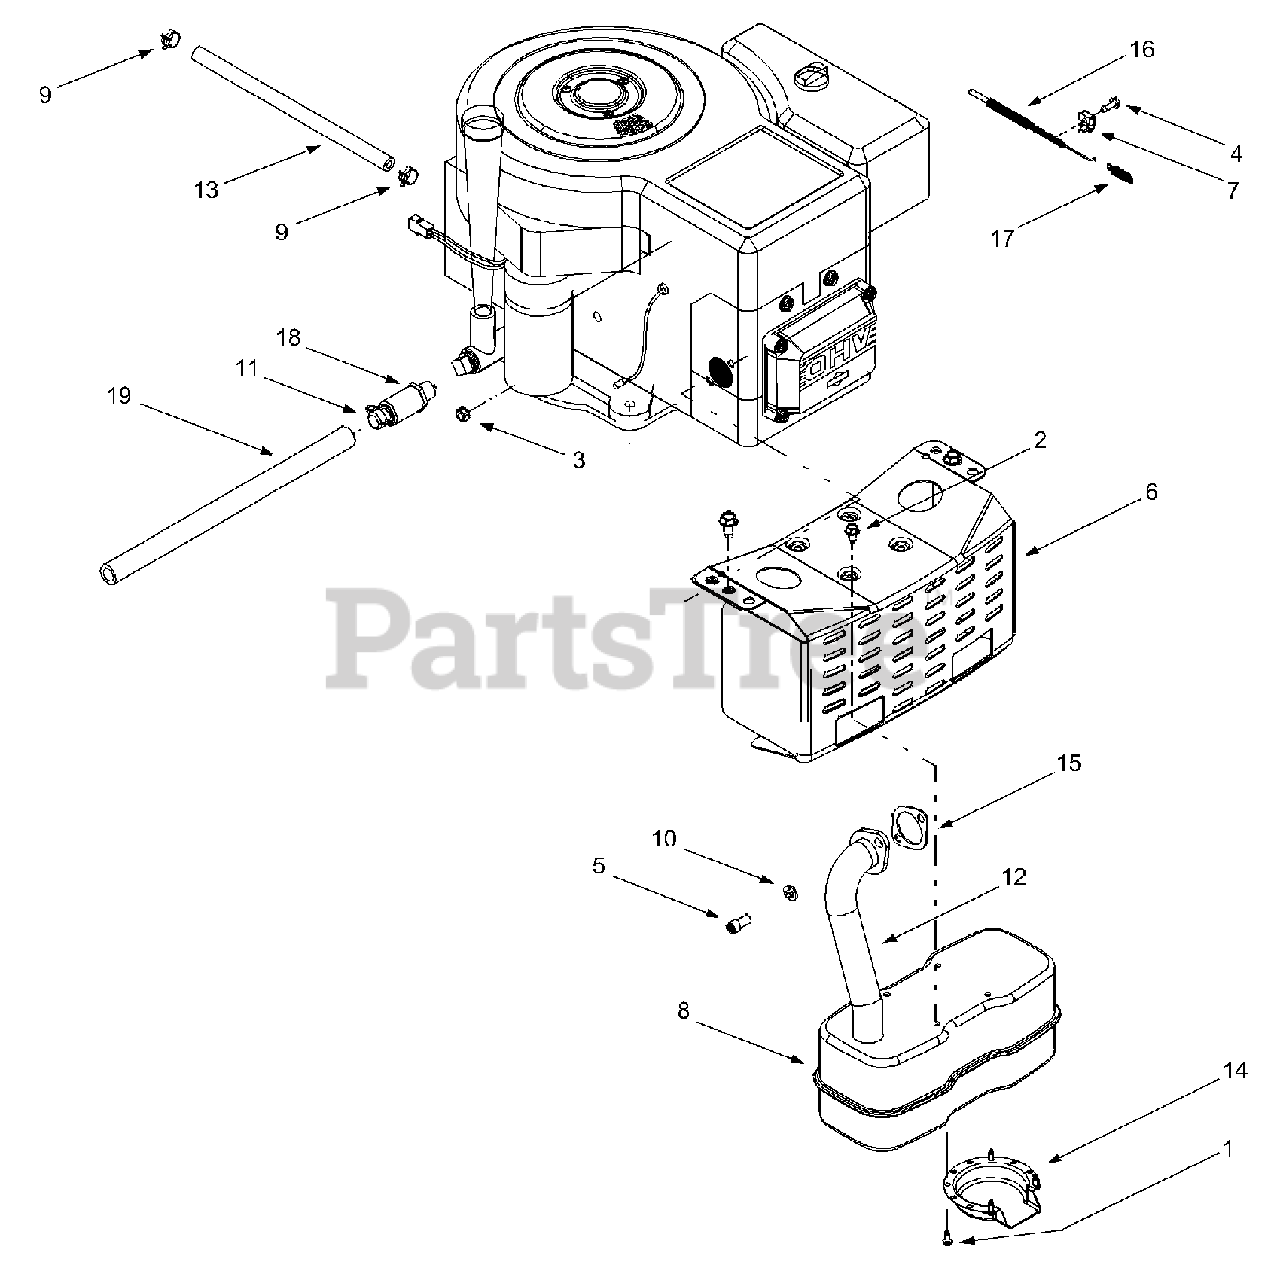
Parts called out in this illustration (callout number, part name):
1	Self-tapping Screw, #8-18 x .50
2	Self-tapping Screw, 1/4-20 x .50
3	Hex Sems Nut, 1/4-20
4	Screw, #10-32 x .625
5	Socket Cap Screw, 5/16-18 x .625
7	Casing Clamp
8	Muffler, Single Inlet
9	Hose Clamp
10	Lock Washer, 5/16
11	Oil Drain Cap
12	Exhaust Pipe
13	Fuel Line Hose
14	Muffler Deflector
15	Exhaust Gasket
16	Throttle Cable
17	Extension Spring, .275 x 1.25
18	Oil Drain Valve
19	Oil Drain Hose
